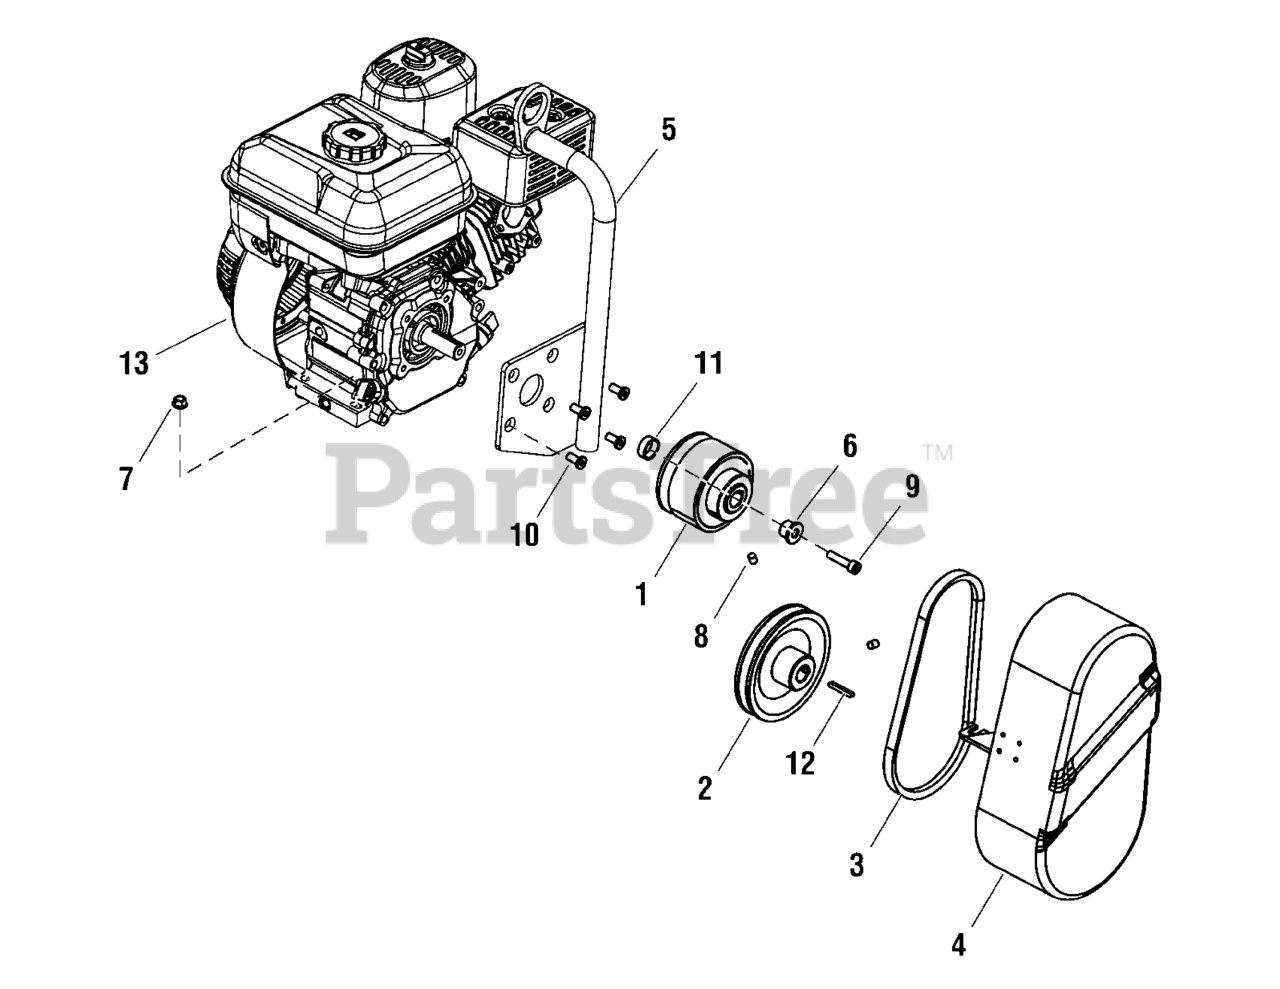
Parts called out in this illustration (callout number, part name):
1	CLUTCH ASSEMBLY
2	PULLEY
3	BELT, A-26
4	BELT COVER
5	HOOK, Lifting
6	LOCATING BUSHSHING
7	NUT, Hex Flange, M8
8	SETSCREW, Hex Socket Head, M8 x 10
9	BOLT, Hex Socket Head, M8 x 35
10	SCREW, Hex Socket Head, Countersunk, M8 x 20
11	BUSHING, Clutch Spacer
12	KEY, B5 x 35
13	ENGINE
